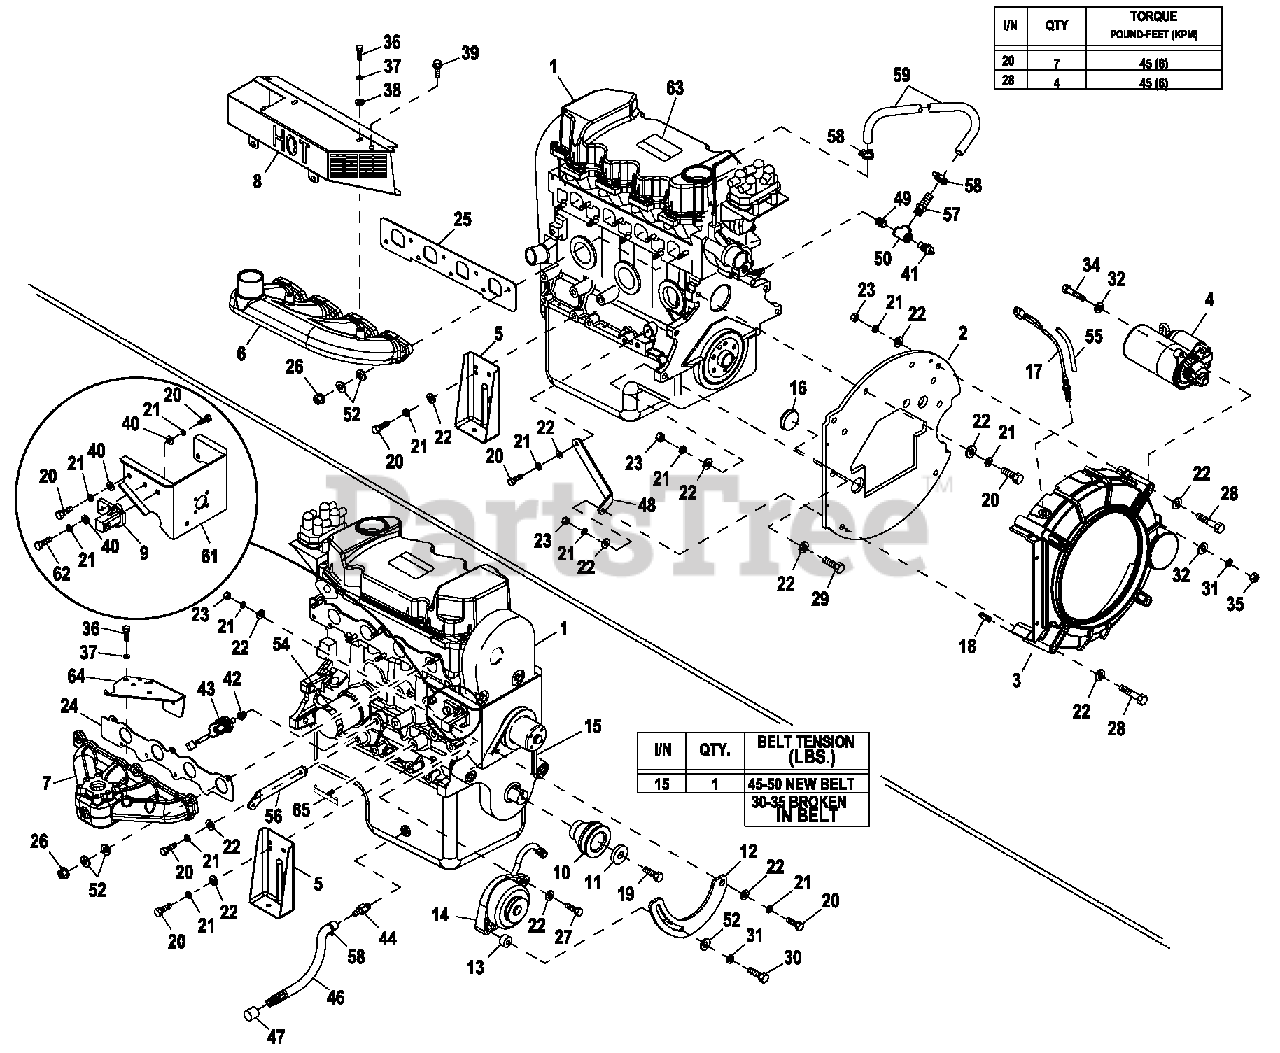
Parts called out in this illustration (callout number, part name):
1	ENGINE GENERAC 1,6L G11 CERT
2	ENGINE PLATE 1.6L6MM (TO BE USED WITH PLATE SPACER P/N 0G2070A.)
3	HOUSING BLOWER LG PILOT
4	STARTER MOTOR 12V
5	ENGINE MOUNTING FOOT STAMPING
6	EXHAUST MANIFOLD 1.6L MACHINED
7	INTAKE MANIFOLD MACHINED 1.6L
8	SHIELD 1.6L EXHAUST HEAT
9	DC ALTERNATOR ADAPTER MACHINED
10	PULLEY CRANKSHAFT MACHINED
11	WASHER PULLEY
12	BRACKET TENSIONER DC ALT
13	SPACER ALTERNATOR
14	DC ALTERNATR HAN-KOK
15	V-BELT 3/8X30.6
16	CAP, 1.5" HOLE SHALLOW
17	ASSY MAGPICKUP (3/8-24 MALE)
18	PIN SPRING 1/4 X 3/4
19	SCREW HHC M12-1.5 X 40 G10.9
20	SCREW HHC M10-1.5 X 25 G10.9
21	WASHER LOCKM10
22	WASHER FLAT 3/8-M10 ZINC
23	NUT HEX M10-1.5 CLASS 10 ZINC
24	GASKET INTAKE MANIFOLD 1.6L
25	GASKET EXHAUST MANIFOLD 1.6L
26	NUT TOP LOCK FL M8-1.25
27	SCREW HHC M10-1.5 X 70 G8.8
28	SCREW HHC M10-1.5X110 G10.9
29	SCREW HHC M10-1.5 X 40 G10.9
30	SCREW HHC M8-1.25 X 35 G8.8
31	WASHER LOCK M8-5/16
32	WASHER FLAT 5/16-M8 ZINC
33	TIE WRAP UL 7.4" X .19" BLK
34	SCREW HHC M8-1.25 X 40 G8.8
35	NUT HEX M8-1.25 G8 CLEAR ZINC
36	SCREW HHC 1/4-20 X 1/2 G5
37	WASHER LOCK M6-1/4
38	WASHER FLAT 1/4-M6 ZINC
39	SCREW HHTT M6-1.0 X 12 ZINC
40	WASHER FLAT M10 HEAVY DUTY
41	TEMPERATURE SENDER, DELPHI
42	BSHG RDCR HEX 1/4 TO 1/8
43	HARN LOW OIL PRESS SWITCH ASSY
44	ADAPTER DRAIN OIL
46	HOSE OIL DRAIN ASSY 21"
47	CAP HEX 1/4 NPT BRASS
48	STRUT LH 1.6L ENG ADAPT PLATE
49	NIPPLE PIPE 3/8 NPT X 1-1/2
50	PIPE TEE 3/8 NPT
51	SCREW HWHTF M6-1.0X16
52	WASHER FLAT .34 ID X .75 OD
54	OIL FILTER 1.6L
55	CONDUIT FLEX .25"ID (6" LG)
56	STRUT RH 1.6L ENG ADAPT PLATE
57	BARBED STR 3/8 NPT X 3/8
58	CLAMP HOSE .38-.87
59	HOSE COOLANT 3/8 ID 20R3 (11" LG)
61	BRACKET FAN ALT ADAPTER 1.6L
62	SCREW HHC M10-1.5 X 35 G8.8
63	DECAL EMISSION CTRL INFO 1.6L
64	BRACKET STEPPER MOTOR COOLANT
65	ANCHOR HARNESS
